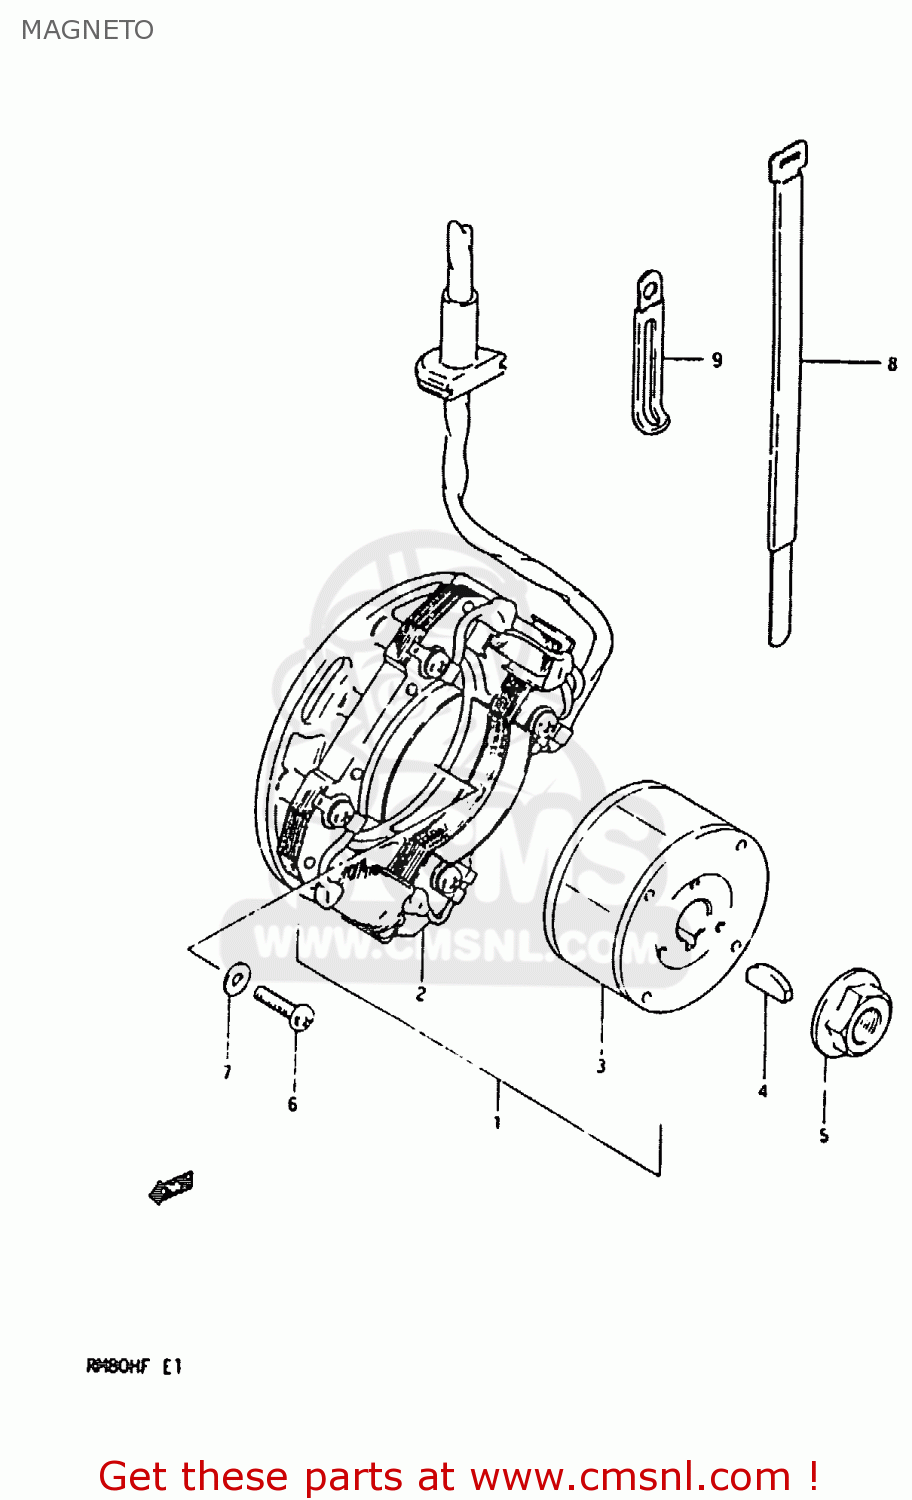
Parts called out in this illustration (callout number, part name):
1	MAGNETO ASSY
2	STARTER ASSY
3	ROTOR ASSEMBLY
4	KEY 4MM
5	NUT
6	SCREW
7	WASHER
8	CLAMP(L:250)
9	CLAMP L:35
